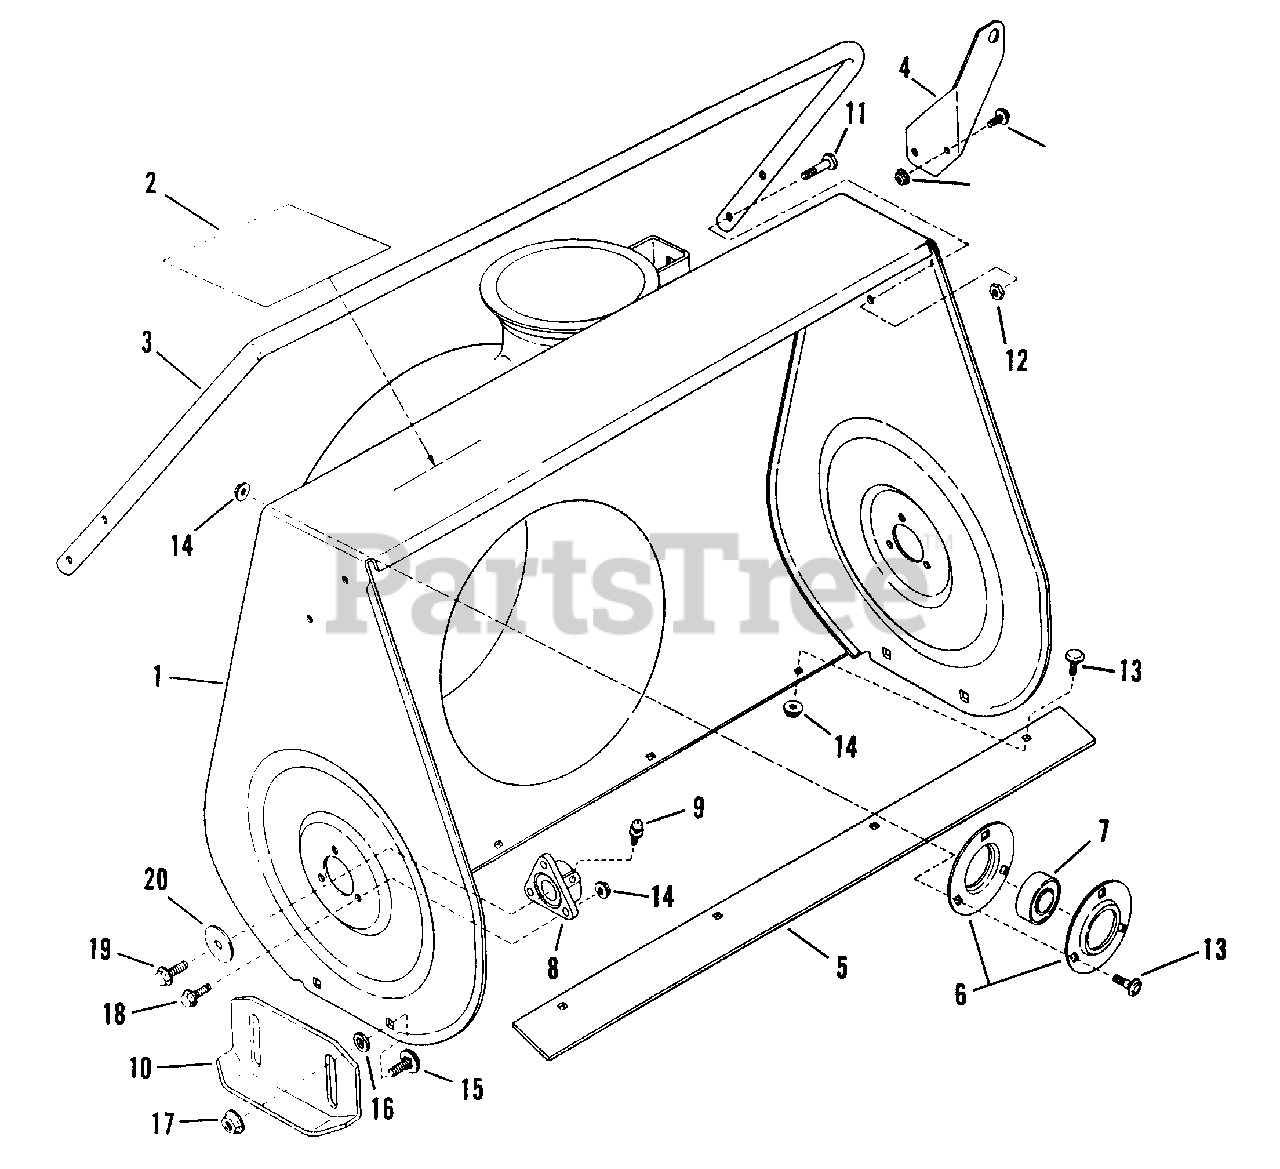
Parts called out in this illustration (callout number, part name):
1	ASSY, Blower Hsg. (22" Models)
2	DECAL, Foot Danger
3	DRIFT-CUTTER (22" Models)
4	BRACKET, Worm Shaft Support
5	BLADE, Scraper (22" Models)
6	HOUSING, Bearing
7	BEARING, Ball
8	BEARING, Auger Shaft
9	FITTING, Lube (Press fit for .187 hole-no ball)
10	SKID-SHOE
11	SCREW, 1/4 - 20 x 7/8 HH Cap
12	NUT, 1/4 - 20 H. Center Lock
13	BOLT, 1/4 - 20 x 5/8 S.N. Carr.
14	NUT, 1/4 - 20 H. Flange Lock
15	BOLT, 5/16 - 18 x 5/8 Carriage
16	WASHER, 5/16 Flat
17	NUT, 5/16 - 18 H. Flange Lock
18	BOLT, 1/4 - 20 x 3/4 H. Flange Lock
19	SCREW, 5/16- 18 x 5/8 Self-Tapping
20	WASHER, Flat
